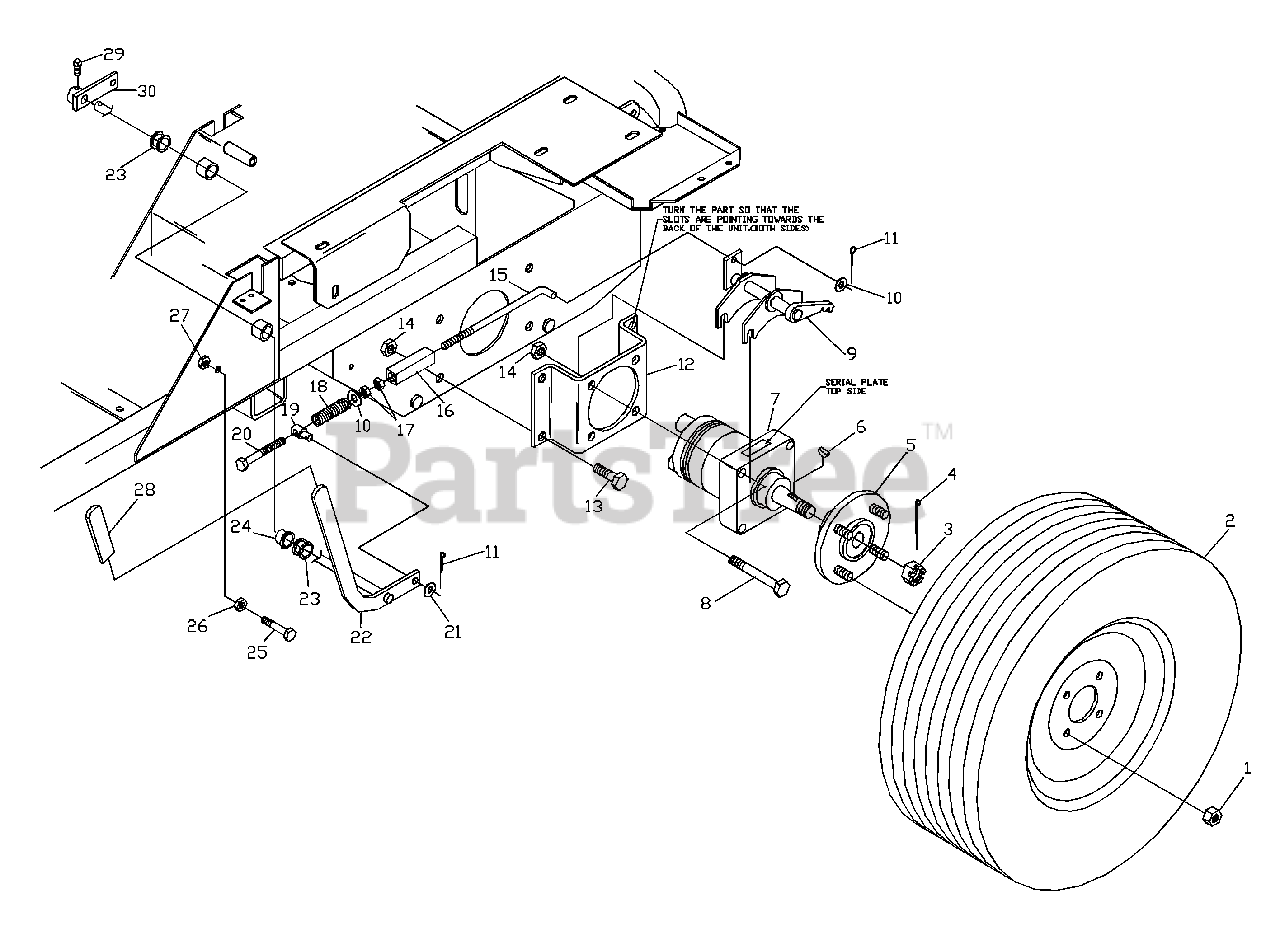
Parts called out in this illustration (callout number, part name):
1	LUG NUT 1/2F
2	REAR TIRE ASM.(COMPLETE)
2	RIM
2	VALVE STEM
3	HEX SLOTTED NUT
4	COTTER PIN
5	HUB, W/SPROCKET
6	KEY, #808 WOODRUFF
7	WHEEL MOTOR
8	HCS 1/2C X 2 3/4
9	BRAKE WELDMENT LEFT
10	WASHER 5/16 FLAT
11	1/8 X 3/4 COTTER PIN
12	MOTOR STANDOFF
13	HCS 1/2C X 1 1/4 SERRATED HEAD
14	NUT 1/2C NYLOC
15	BRAKE LINKAGE
16	TURNBUCKLE
17	5/16C HEX NUT
19	BRAKE SWIVEL
20	HCS 5/16C, SPECIAL
21	WASHER 3/8 FLAT
22	PIVOT SHAFT
23	7/16 DISC SPRING WASHER
25	HCS 3/8C X 1 3/4
26	3/8C WHIZ NUT
27	NUT 3/8C CENTERLOCK
29	5/16C X 5/8 SQ. HEAD
30	ARM, PARK BRAKE
